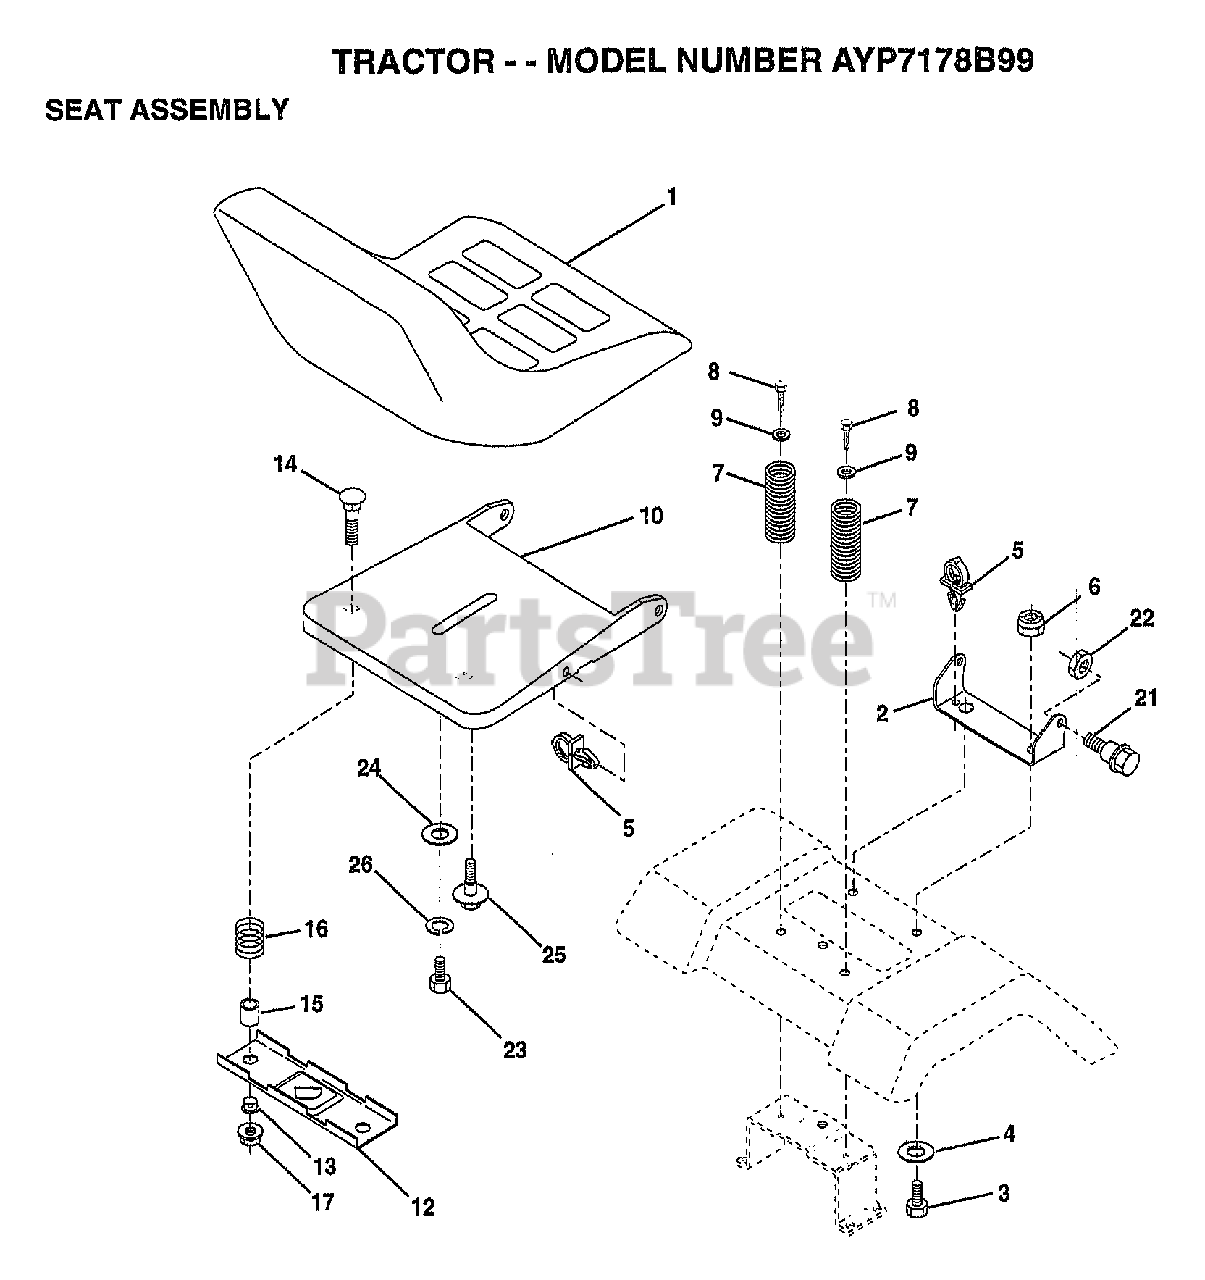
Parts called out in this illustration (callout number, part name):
1	SEAT.2400/1416.BK
2	BRACKET PVT SEAT
3	BOLT
4	WASHER PM
5	CLIP.PUSH-IN.HING
6	NUT
7	SPRING COMPRESSIO
8	SCREW GTV
9	WASHER
10	PAN-SEAT
12	BRKT SWITCH
13	BUSHING
14	BOLT-RD HD SQ NK
15	SPLIT SPACER
16	SPRING
21	"BOLT,SHOULDER"
22	NUT
23	BOLT
24	WASHER
25	"BOLT,SHOULDER"
26	LOCKWASHER
